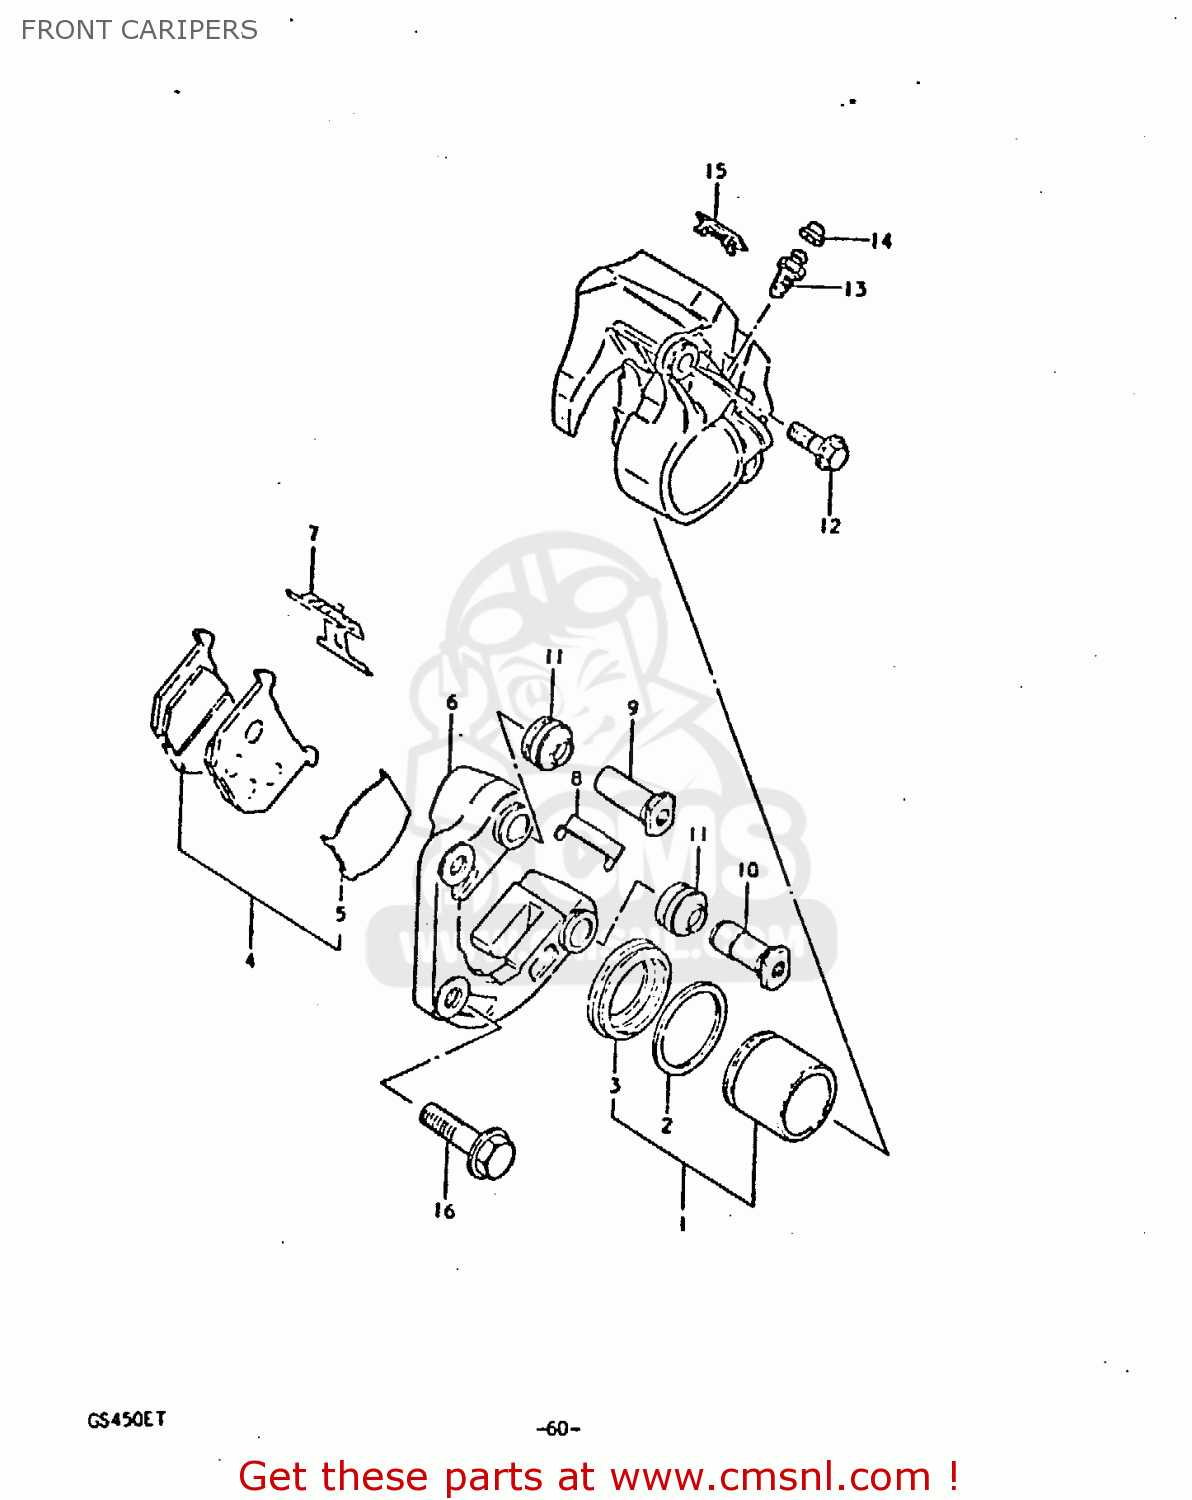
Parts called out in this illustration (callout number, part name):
1	PISTON SET
2	SEAL,FR CALIPE
3	BOOT,PISTON
4	PAD SET (MCA)
5	SHIM,PAD
6	BRACKET
7	SPRING,PAD
8	GUIDE,PAD
9	AXLE NO.1
10	AXLE NO.2
11	BOOT,AXLE
12	BOLT,CALIPER HOUSING
13	BLEEDER
14	CAP,BREATHER
15	COVER,INDICATOR
16	BOLT(10X37)
